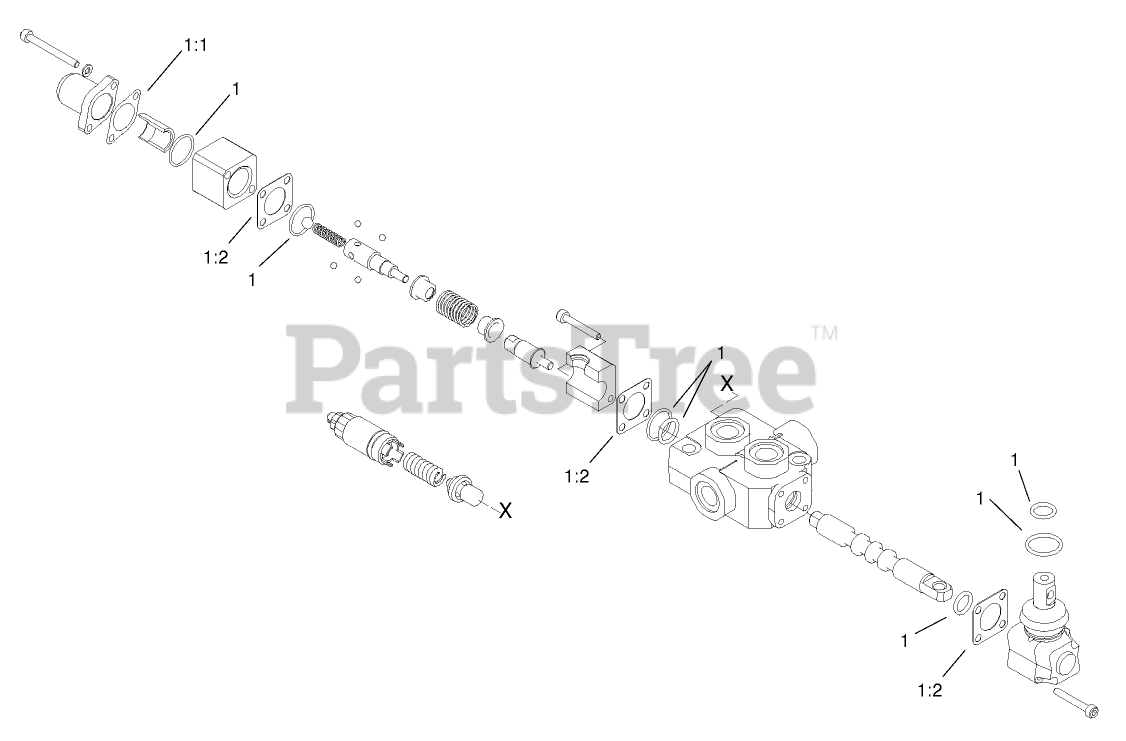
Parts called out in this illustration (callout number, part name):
1	SEAL KIT
1:1	GASKET
1:2	GASKET
